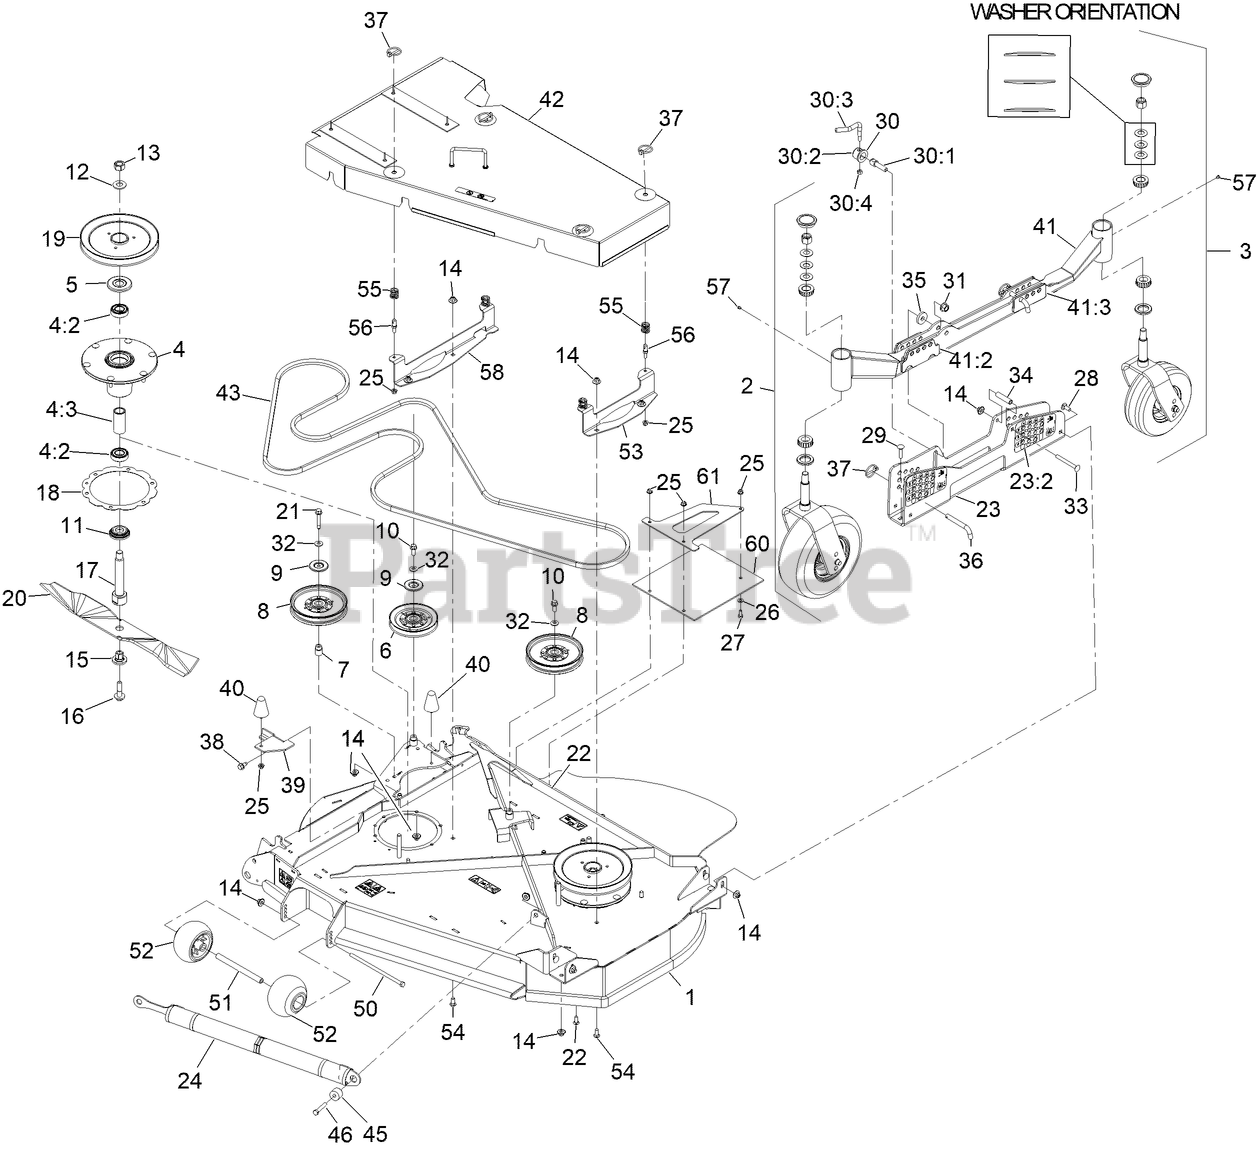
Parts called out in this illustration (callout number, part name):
1	ASM-LH WING DECK 144
2	CASTER WHEEL ASM
3	REAR CASTER WHEEL ASM
4	SPINDLE ASM
4:2	BEARING-BALL
4:3	SPACER-BEARING
5	GUARD-BEARING, TOP
6	IDLER-V
7	BUSHING-IDLER
8	IDLER-PULLEY
9	SHIELD-DUST
10	SCREW-HHF
11	GUARD-BOTTOM
12	WASHER
13	NUT-HEX
14	NUT-FLANGE, NI
15	BUSHING-HEX
16	SCREW-SEMS
17	SHAFT-SPINDLE
18	RING-SPACER, HOUSING
19	SHEAVE-DRIVE, BLADE
20	BLADE-24.50 MULCH
21	SCREW-HHF W/ PATCH
22	BOLT-CARR
23	ASM-CHANNEL, HOC LH
23:2	DECAL-HEIGHT OF CUT-LH
24	ASM-WEIGHT-TRANSFER-SPRING
25	NUT-HF, NI
26	WASHER-PLAIN
27	SCREW-HH
28	BOLT-CARR
29	SCREW-CARR
30	LEVER ASM
30:1	SCREW-LOCK
30:2	CAP-LOCK
30:4	NUT-LOCK, NI
31	NUT-LOCK
32	WASHER-BELLEVILLE
33	SCREW-CARR
34	SPACER
35	WASHER
36	PIN-HOC
37	PIN-LYNCH
38	SCREW-HWH
39	BRACKET-COVER RETAINER
40	BUMPER-RUBBER
41	ASM-LH GAUGE WHEEL ARM
41:2	PLATE-GUIDE, FRONT
41:3	PLATE-GUIDE, REAR
42	ASM-BELT SHIELD
45	BUSHING-LIFT SPRING
46	SCREW-HH
50	SCREW-HH
51	SPACER-WHEEL
52	ROLLER-SCALP, ANTI
53	BRACKET-SHIELD MOUNT, OUTER
54	BOLT-CARR
55	SPRING
56	PIN, SPRING
58	BRACKET-SHIELD MOUNT, OUTER LONG
60	GUARD-LH REAR WING
61	SUPPORT-LH REAR GUARD
